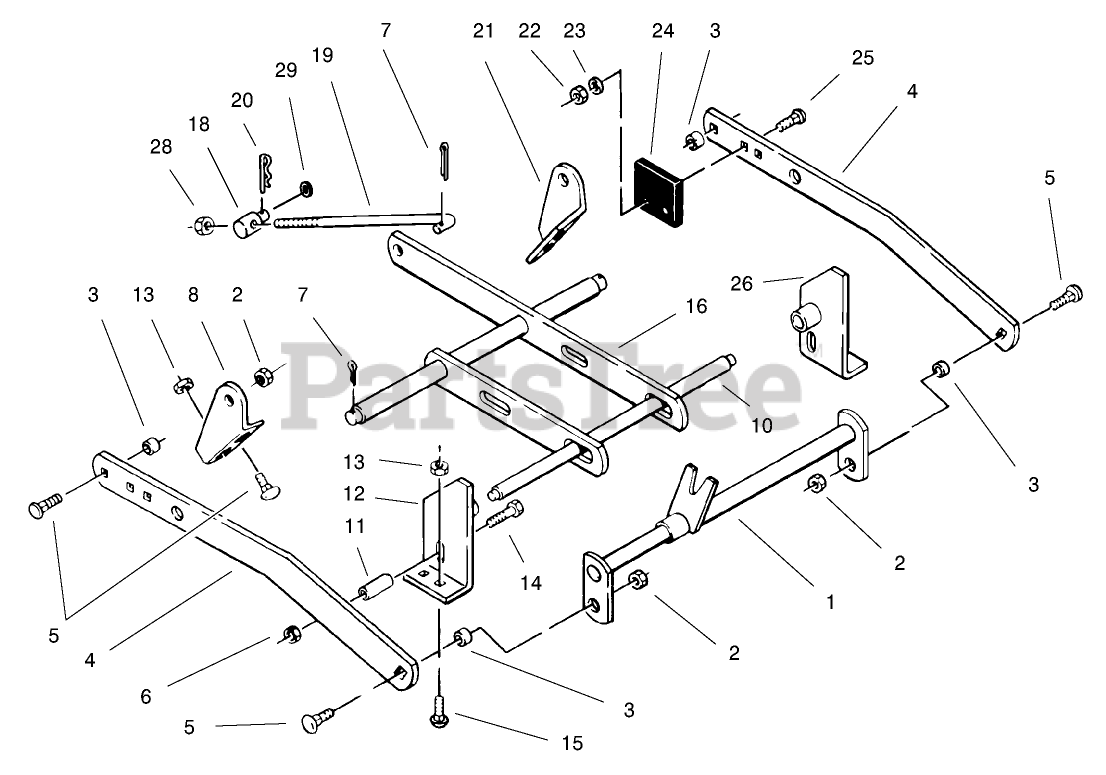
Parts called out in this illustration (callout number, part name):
1	WA HITCH
3	SPACER
4	BAR DRAFT
5	BOLT-CARR
6	NUT-LOCK, NI
7	PIN-COTTER
8	BRACKET-DCK R
11	SPACER
12	WA-RH FRT DK BRK
13	NUT-LOCK, NI
14	BOLT-CARR
15	BOLT-CARR
16	WA-LEVELER BAR
18	TRUNNION
19	LIFT ROD
20	PIN-HAIR
21	BRACKET-DCK L
22	NUT-LOCK, NI
23	WASHER-FLAT
24	BUMPER
25	SCREW-CARR
26	WA-LH FRT DK BRK
28	NUT-LOCK, NI
29	WASHER-FLAT
